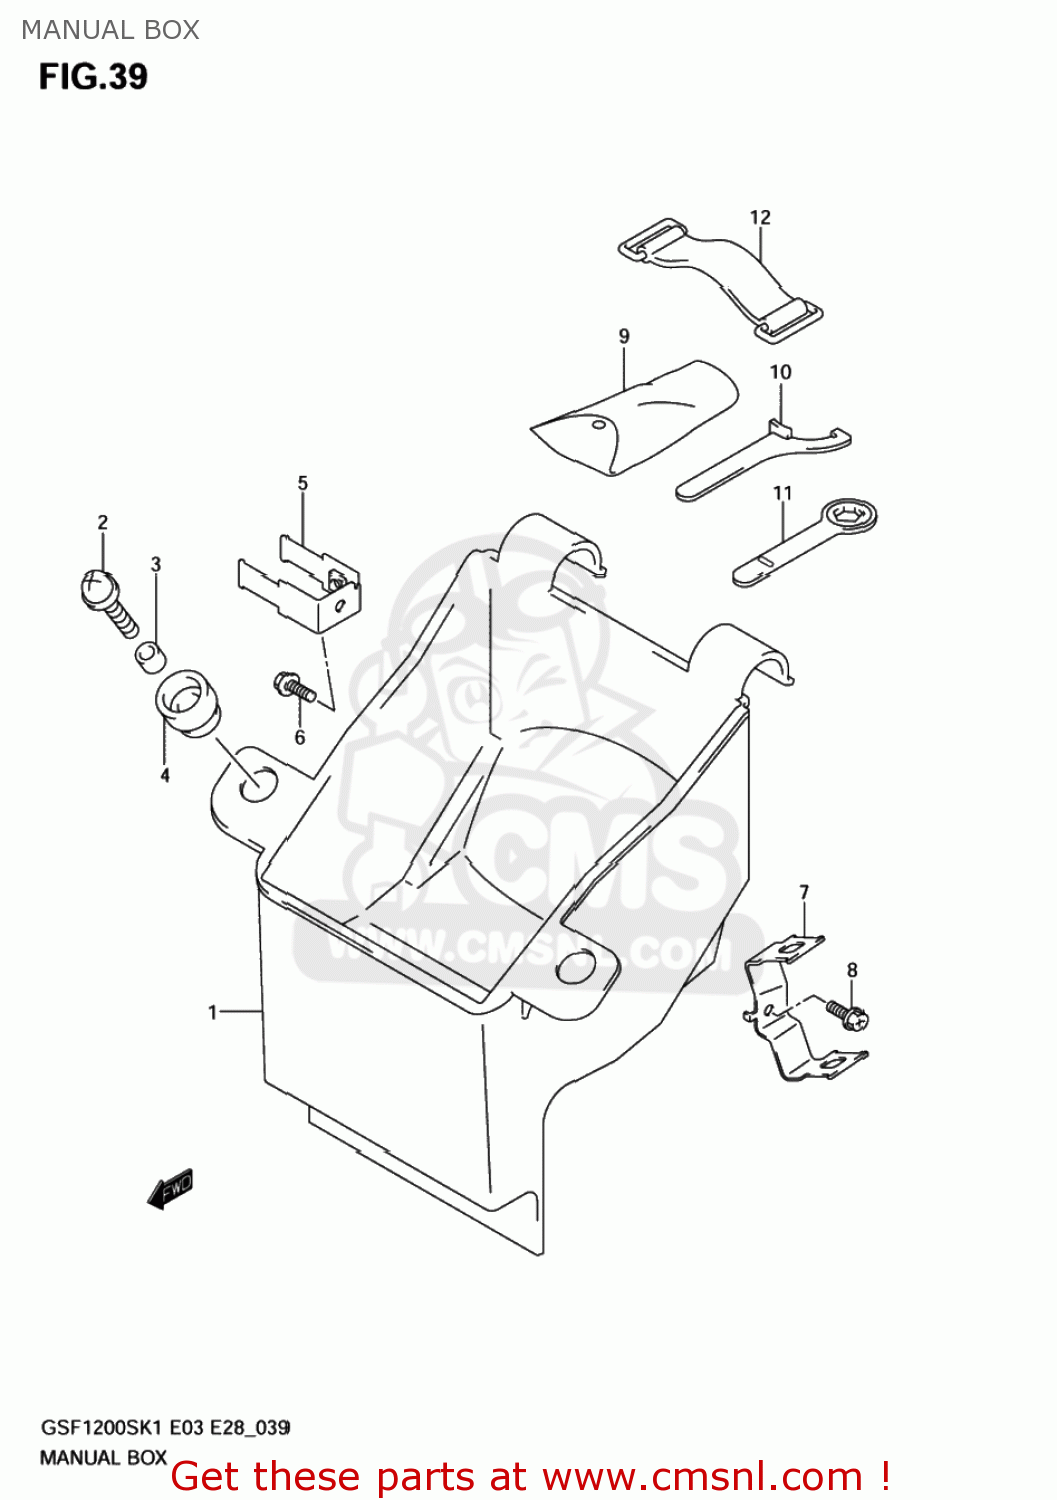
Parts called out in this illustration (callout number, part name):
1	BOX,MANUAL
2	SCREW(6X20)
3	SPACER(6.5X10X8)
4	CUSHION
5	PLATE,RLY FITING
6	BOLT
7	PLATE,IGNITOR FITING
8	BOLT
9	TOOL ASSY
10	CLAMP
11	RING,SPANNER(24)
12	BAND
